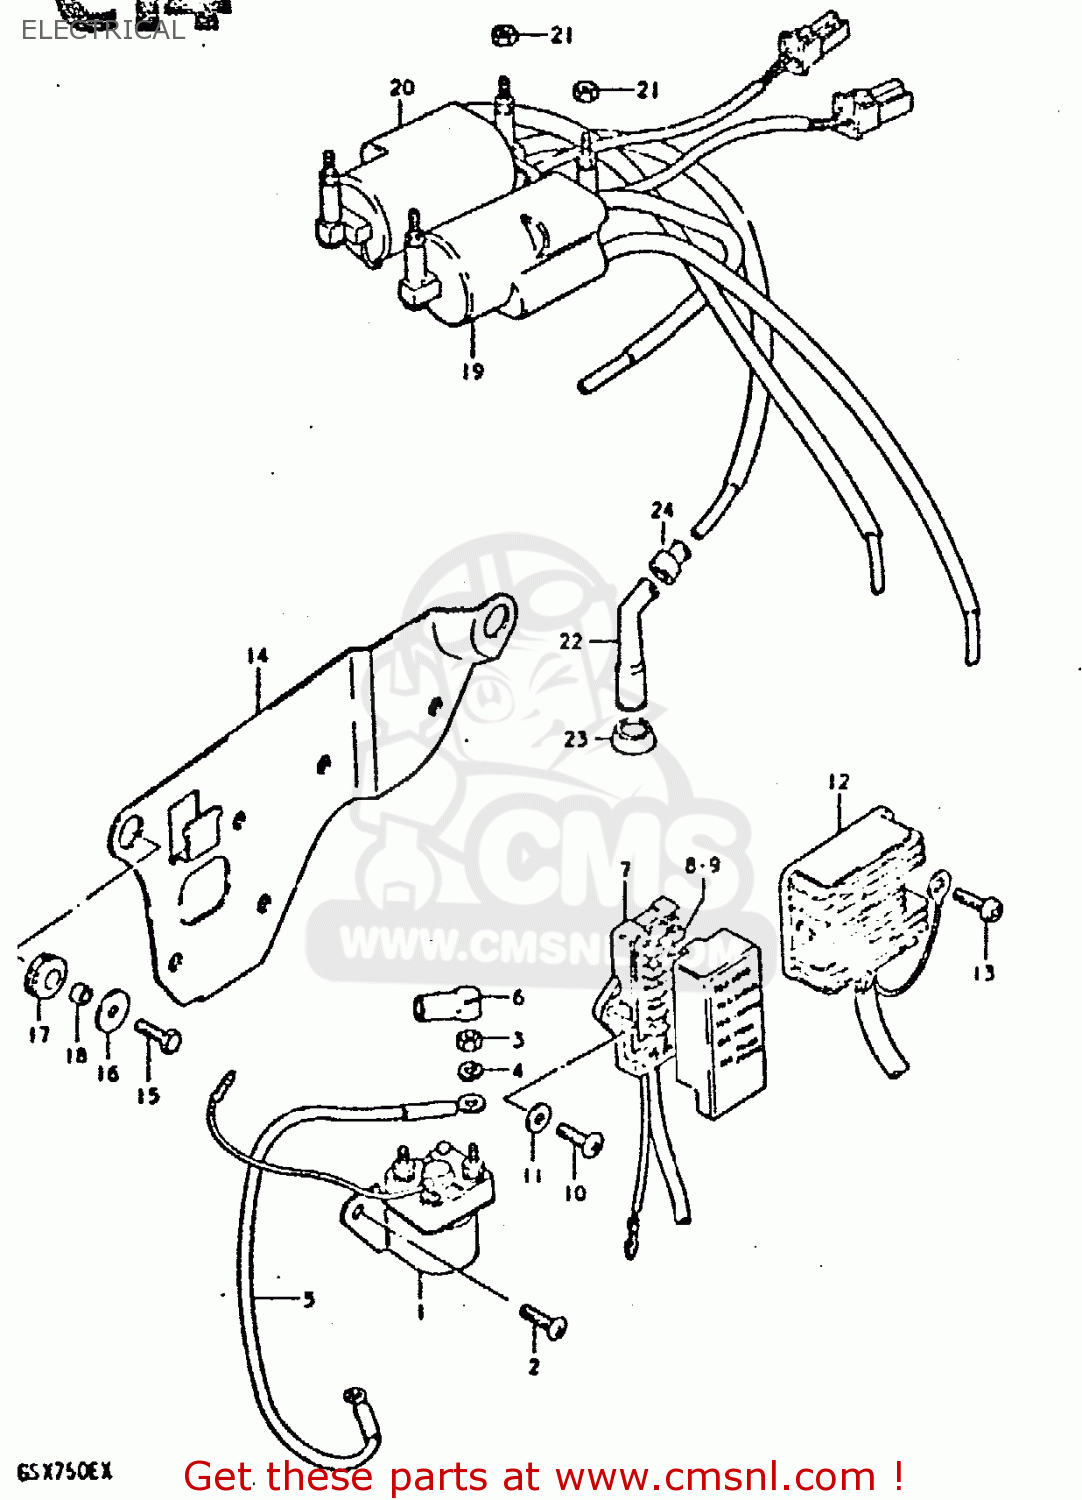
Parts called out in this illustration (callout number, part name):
1	RELAY ASSY,STARTING MOTOR
2	SCREW
3	NUT 6MM
4	LOCK WASHER
5	WIRE,STARTER MOTOR LEAD
6	CAP,STARTER RELAY
7	BOX ASSEMBLY,FUSE
8	FUSE(10A)
9	FUSE(15A)
10	SCREW
11	WASHER
12	RECTIFIER ASSEMBLY
13	SCREW 6X12
14	PLATE,ELECTRIC PARTS HOLDER
15	BOLT, UPPER
16	WASHER(6,5X22X1.6)
17	CUSHION
18	SPACER (7X9X7)
19	COIL ASSEMBLY,IGNITION
20	COIL ASSEMBLY,IGNITION
21	NUT
22	CAP ASSY,SPARK PLUG
23	SEAL,SPARK PLUG
24	SEAL,SPARK PLU
